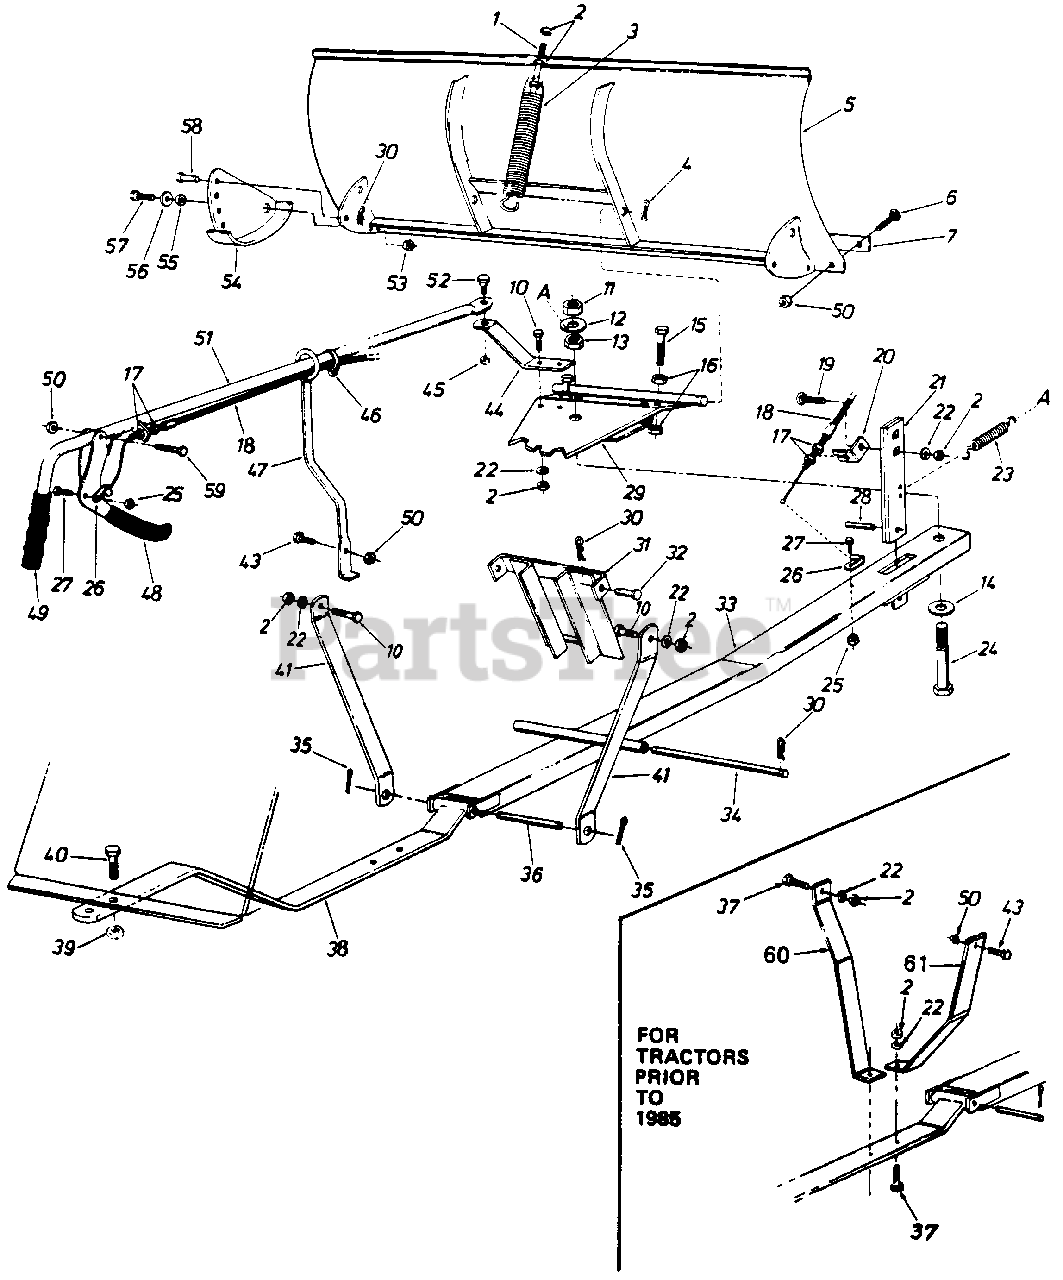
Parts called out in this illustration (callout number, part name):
1	Hex Scr. 3/8-16 x- 0 450 4.
2	HexNut 3/8-16 Thd.*
3	Blade Adjustment Spring
4	Hairpin Clip 5/32" Dia.
5	48" Blade Ass'y.
6	Carriage Bolt 5/16-18 x 75" 4*
7	Wear Plate 48"
10	Hex Scr. 3/8-16 x 1.00 4
11	Hex L.-Nut 3/4-10 0 Thd.
12	Fl.-Wash. .810" I.D. x 2.00" O.D.
13	Hex Jam Nut 3/4-10 0 Thd.*
14	Fl.-Wash. .810" I.D. x 2.00" O.D.
15	Hex Scr. 1/2-13 x 2.00" 4
16	Hex Nut 1/2-13 0 Thd.
17	Hex Jam Nut 5/16- 0 24 Thd.
18	Control Cable Ass'y.
19	Carriage Bolt 3/8-16 x 1.25" 4
20	Cable Guide Bracket
21	Angle-Lock Bar
22	L.-Wash. 3/8" I.D
23	Angle Lock Spring
24	Hex Scr. 3/4-10 x 4.00" Lg.
25	Hex L-Nut 1/4-20 Thd.
26	Clevis Lanyard Fitting
27	Hex Scr. 1/420 x .75" Lg.*
28	Roll Pin 1/4" Dia. x 1.00"
29	Pivot Plate Ass'y. Lg.
30	Hairpin Clip 3/32" Dia.
31	Guide Bracket Ass'y
32	Clevis Pin 1 2" Dia. x 1.00" Lg.
33	Push Bar Ass'y.
35	Cotter Pin 5/32" Dia. x 100" Lg.
37	Hex Scr. 3/8-16 x 1.25" Lg.*
38	Hanger Bracket Ass'y.
39	Hex L.-Nut 5/8-11 Thd
40	Hex Scr. 5/8-11 x 1.50" Lg.*
41	Hanger Link
43	Hex Bolt 5/16-18 x 100" Lg.
44	Blade Pivot Bracket
45	Hex L.-Nut 3/8-16 Thd.
46	Nylon Cable Tie
47	Tube Guide Ass'y.
48	Clutch Grip Ass'y.
49	Grip-3/4" Handle
50	Hex L-Nut 5/16-18 Thd.
51	Tube Handle Ass'y.
52	Shld. Scr.-Special 3/8-16 Thd.
53	Hex L.-Nut 3/8-16 0 Thd.
54	Skid Assembly
55	Spacer
56	Fl.-Wash. .385" I.D. x 1.00" O.D.
57	Hex Scr. 3/8-1ff x4 0 .75" Lg.*
58	Clevis Pin 5/16" Dia. x .75" Lg.
59	Hex Scr. 5/16-18 x 1.50"Lg.
60	Mounting Brkt.-L.H.
61	Mounting Brkt-R.H.
